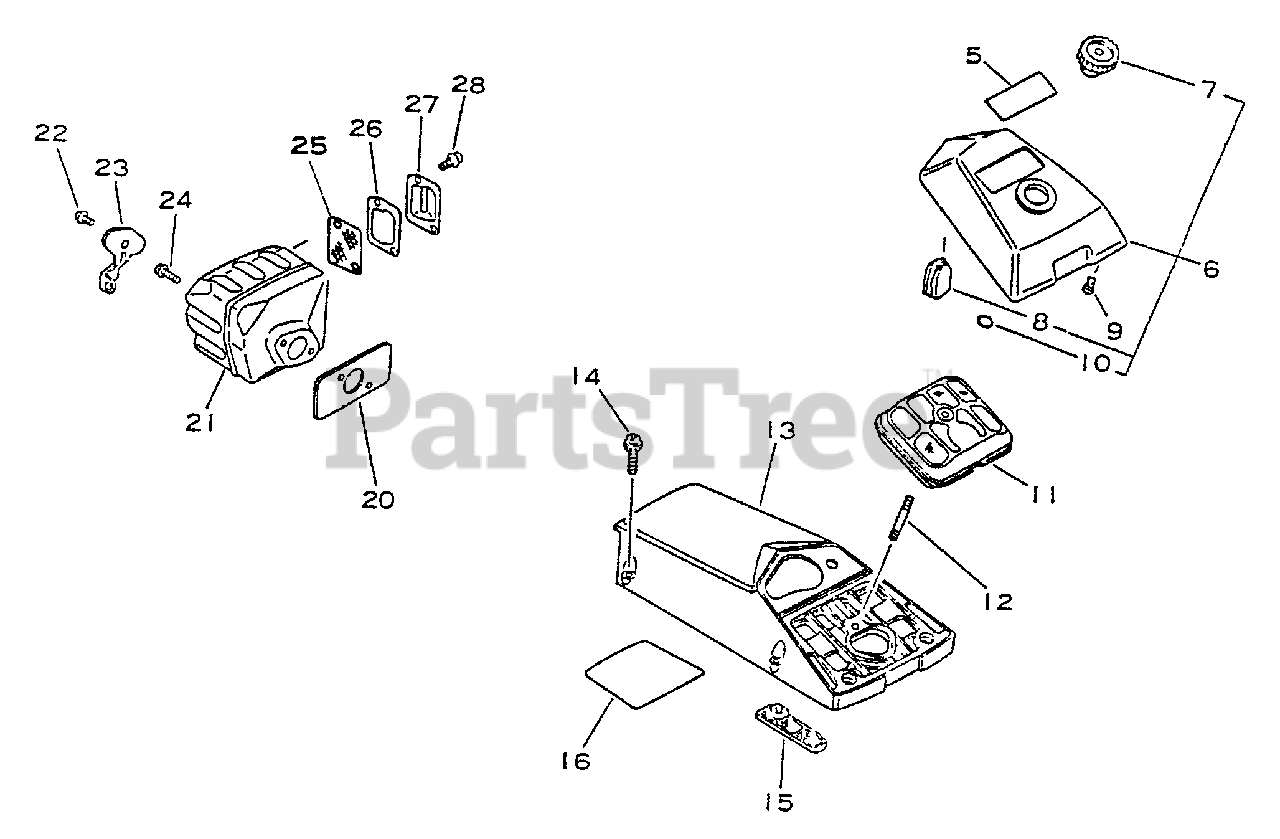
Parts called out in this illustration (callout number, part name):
5	LABEL - MODEL
6	COVER, AIR FILTER
7	WINGNUT
10	O-RING P-11
11	FILTER, AIR
13	COVER, CYLINDER
14	SCREW - 5×20
15	FILTER
20	GASKET, EXHAUST
21	MUFFLER
22	SCREW - 5×10
23	BRACKET, MUFFLER
24	SCREW - 5×20
25	SCREEN, SPARK ARRESTER
26	GASKET, EXHAUST
27	COVER, MUFFLER
28	SCREW - 4×8
